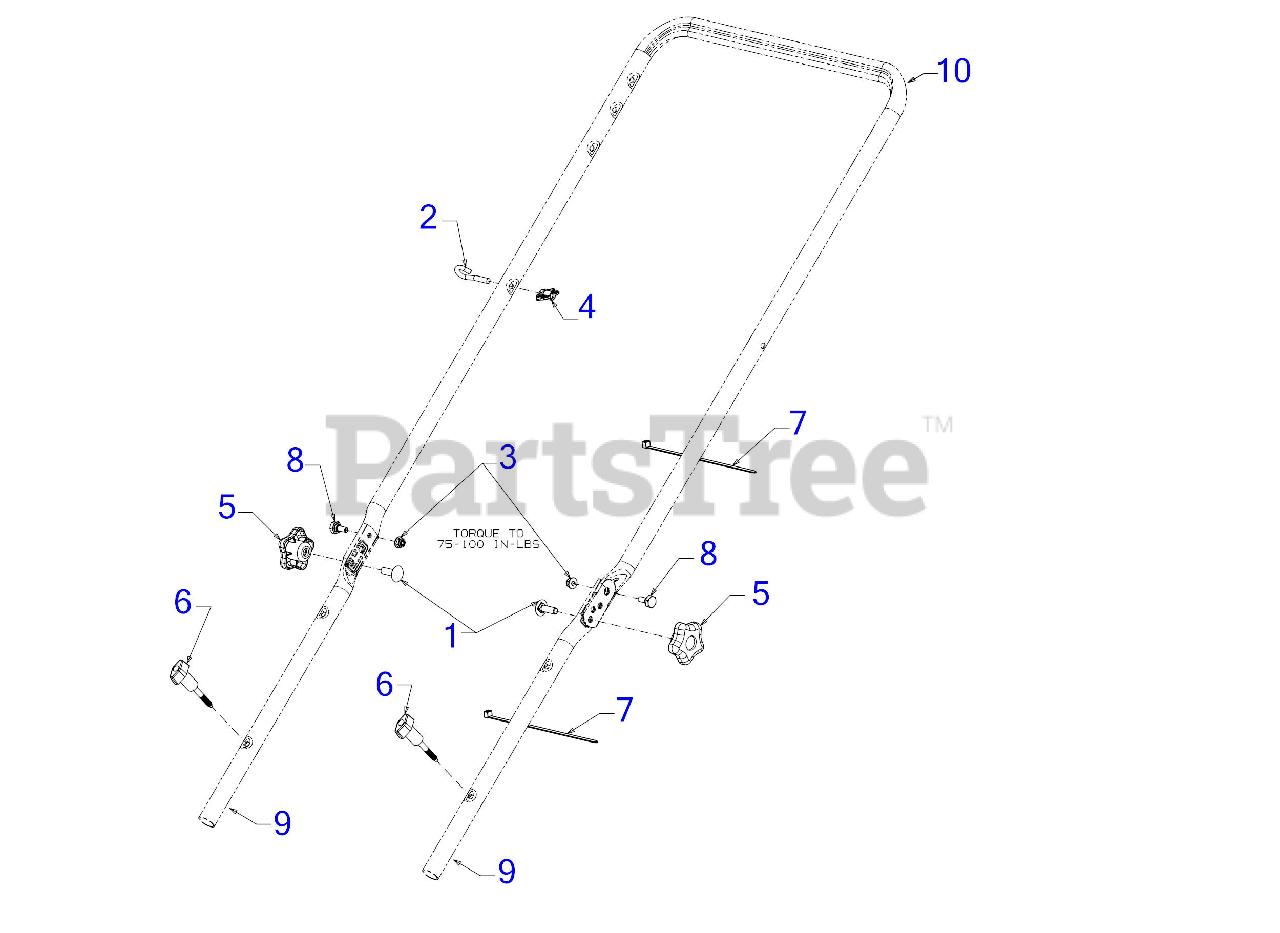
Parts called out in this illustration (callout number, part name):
1	SCREW 5/16-18 x 1.00 GR5
2	EYEBOLT 1/4-20
3	FLANGE LOCK NUT
4	HANDLE KNOB
5	STAR KNOB 5/16-18
6	WING KNOB 1/4-20
7	7" CABLE TIE
8	SHOULDER SCREW
9	LOWER HANDLE
